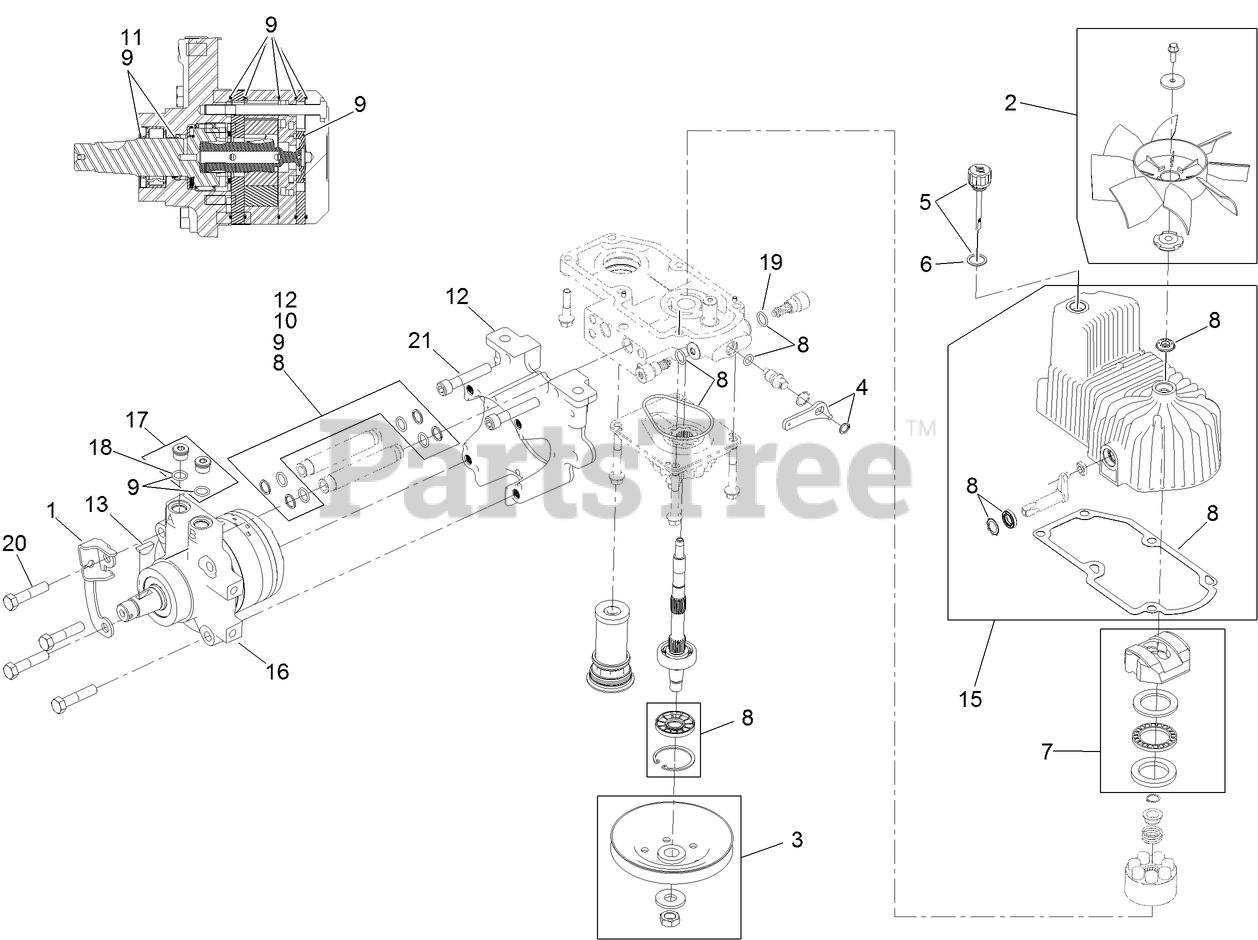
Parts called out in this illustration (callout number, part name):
1	BRACKET-ANCHOR, CABLE
2	FAN KIT
3	PULLEY KIT
4	HANDLE-BYPASS VALVE, HYDRO
5	DIPSTICK-HYDRO W/GASKET
6	GASKET-DIPSTICK, HYDRO
7	SWASH BLOCK KIT
8	PUMP SEAL KIT
9	MOTOR SEAL KIT
10	TUBE SEAL KIT
11	OUTPUT SHAFT SEAL KIT
12	NOSE CUP-UHT
13	KEY-WOODRUFF
15	Housing-LH
16	MOTOR-HYDRAULIC, LH 280CC
17	MAGNETIC PLUGS SERVICE KIT
18	O-RING
19	O-RING-CHECK VALVE
20	SCREW HH
21	SCREW-HSH
